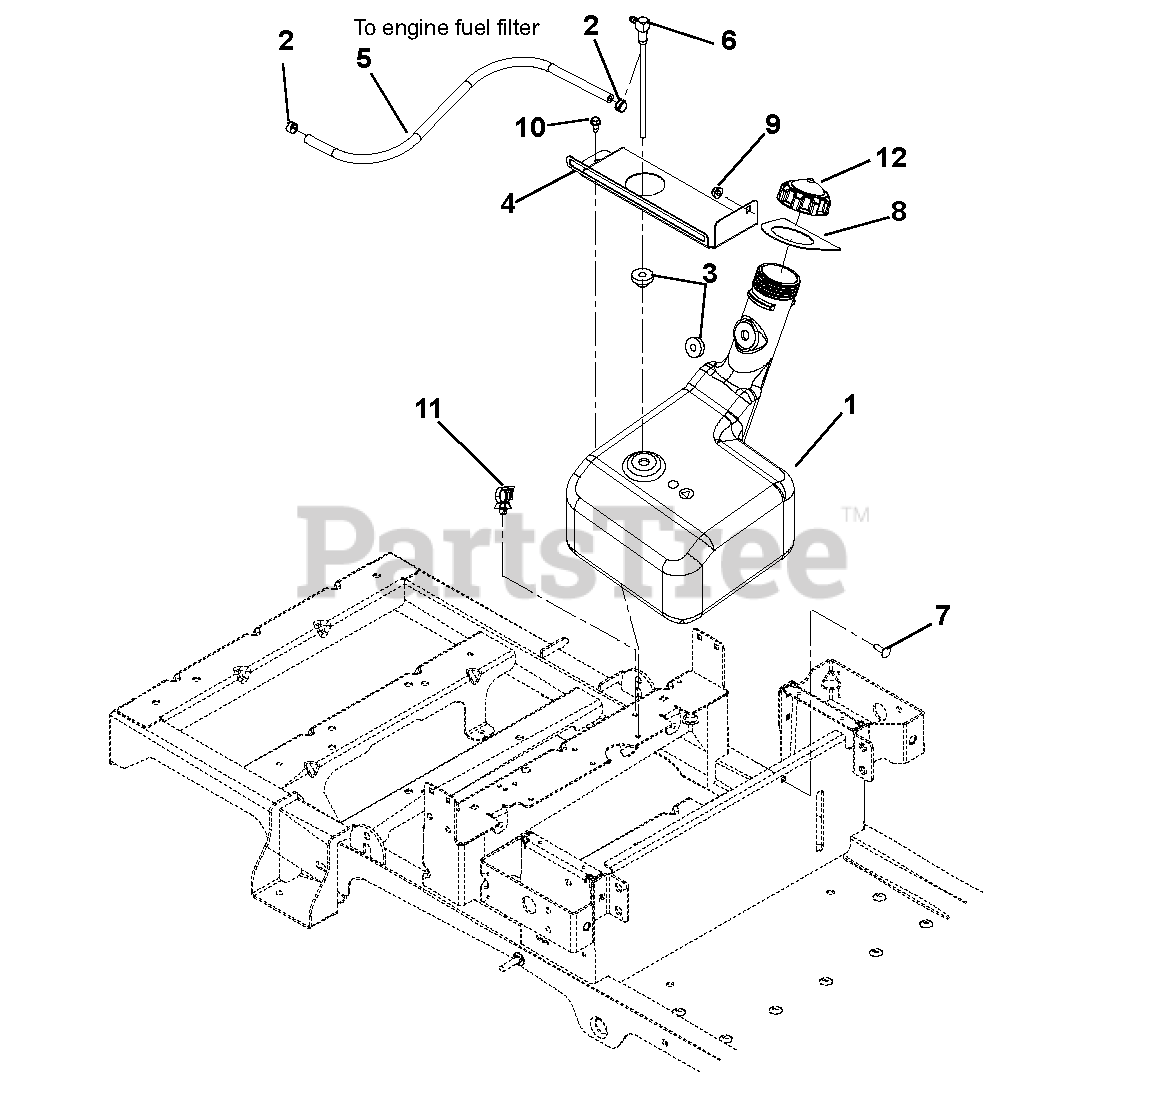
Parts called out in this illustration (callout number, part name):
1	Tank, Fuel
2	Clamp, Fuel Line
4	Bracket, Tank Strap
5	Hose, .25 Low Perm Gas (as required)
6	Assembly, Fuel Pickup
7	Bolt, Round Head Square Neck .25-20 x .75
8	Seal, Tank Neck
9	Nut, .25-20 Nyloc Flange
10	Screw, Tapping .25-20 x .50 Hex Washer Head
11	Wire Clip
12	Fuel Cap
